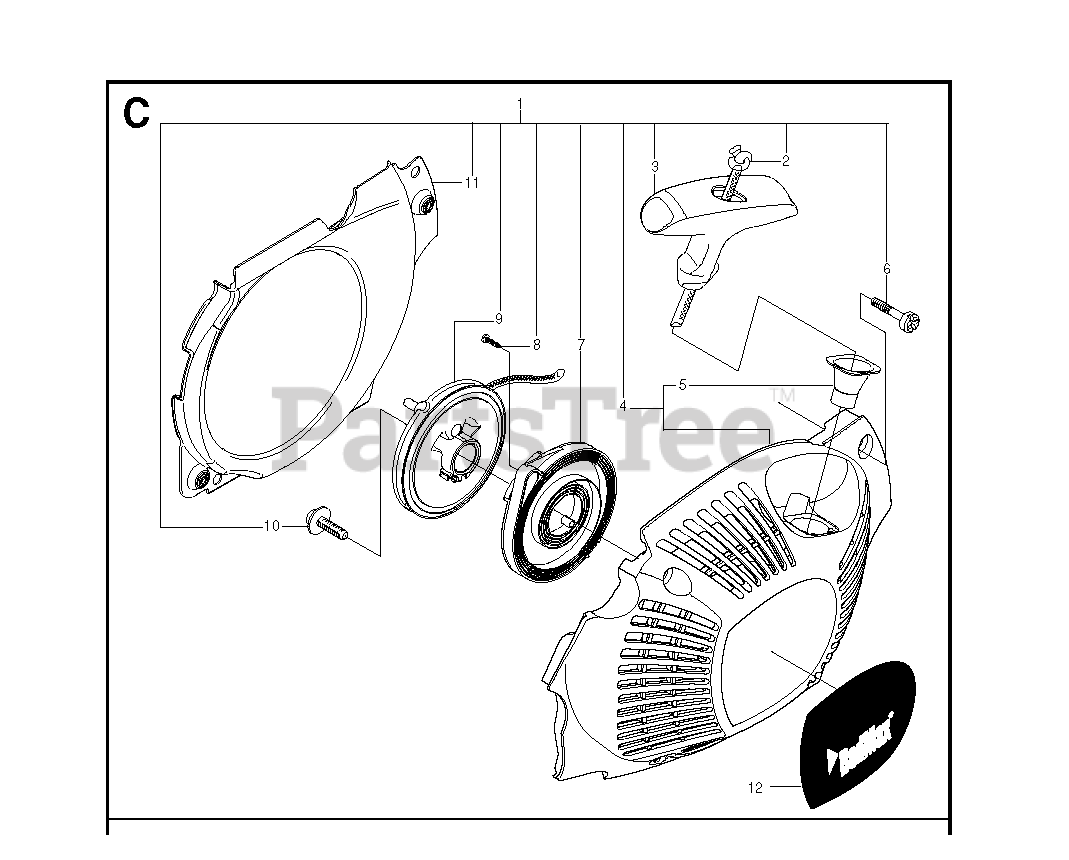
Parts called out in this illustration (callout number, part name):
1	STARTER ASSY
2	STARTER ROPE
3	STARTER HANDLE
5	SLEEVE
7	RP SPRING
9	STARTER PULLEY
